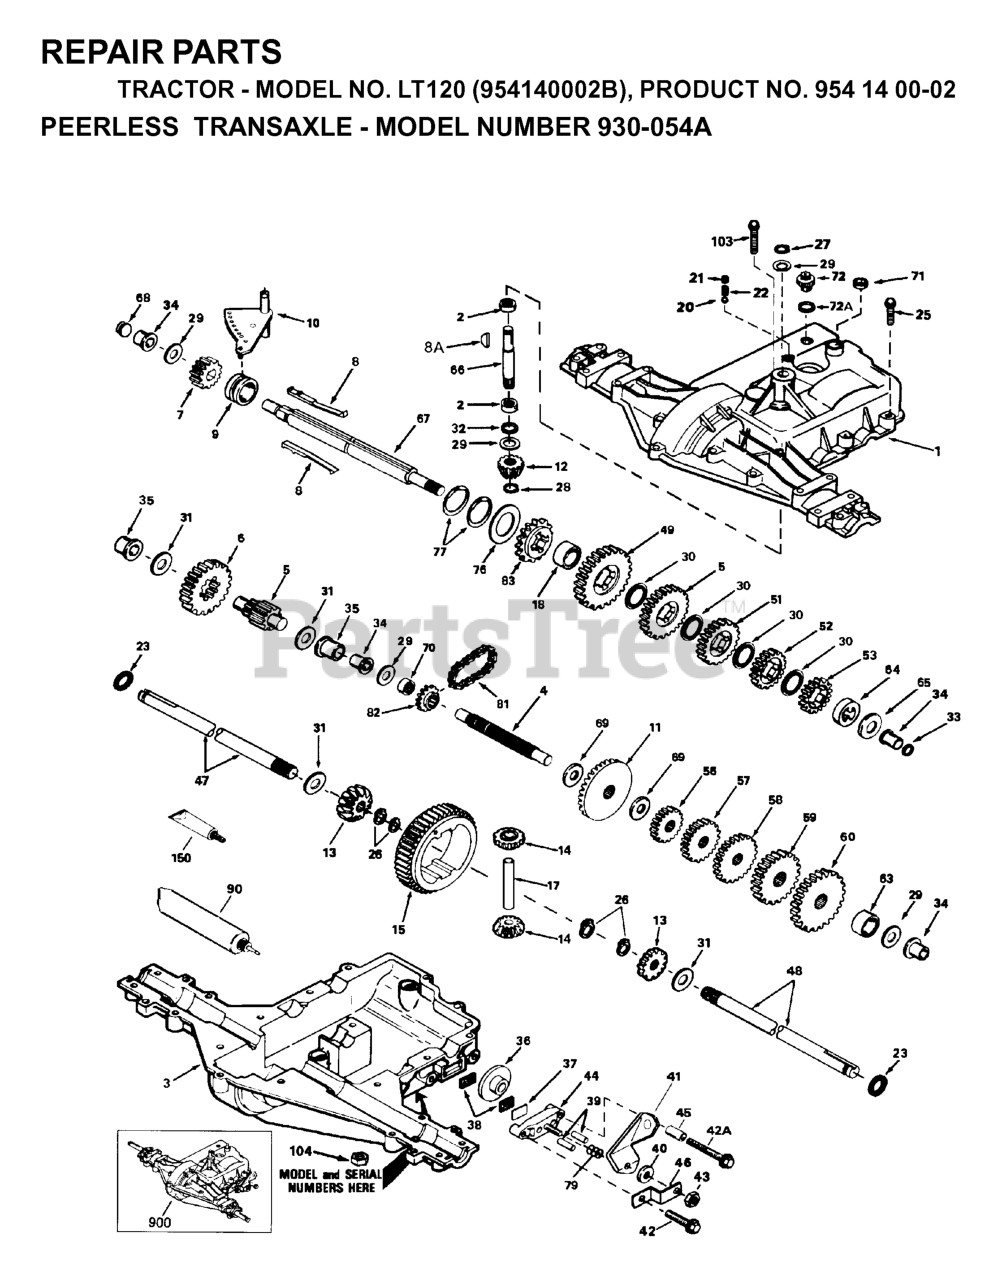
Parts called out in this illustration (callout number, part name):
2	Bearing, Needle
4	Shaft, Counter
8A	Woodruff Key No. 9
9	Collar, Shifter
11	Bevel Gear (42 teeth-steel)
15	Gear, Ring
18	Spacer, Neutral
20	Ball, Steel 5/16" diameter
21	Set Screw 3/18-16 x 3/8"
23	Ring, Seal
26	Ring, Retainer (4 Required, Package of 2)
27	Retaining Ring
28	Ring, Retaining
29	Washer, Thrust
30	Washer, Thrust
31	Washer (.056 wide)
33	Seal, Square Cut
36	Disk, Brake
37	Plate, Brake pad
38	Brake Pad (pkg of 2)
39	Pin, Dowel
40	Washer, Flat
41	Lever, Brake
42	Screw, Flanged Hex Head, Thread Forming 1/4-20 x 1-1/4
42A	Screw, 1 /4-20 x 2-1 /4"
43	Lock Nut 5/16-24
44	Holder, Brake pad
45	Spacer (1/2" OD)
46	Bracket, Brake lever
47	Axle (11-15/16" long)
48	Axle (16-1/2" long)
49	Gear, Spur, 37 Teeth, Steel (1 st)
53	Gear, Spur, 19 Teeth, Steel (4 th)
56	Gear, Spur, 12 Teeth (1 st)
60	Gear, Spur, 31 Teeth (5 th)
63	Countershaft Spacer (1-1/8" x 3/8")
64	Brake Shaft Spacer (1-3/8" x 3/8")
66	Input Shaft (3.687" long)
69	Thrust Washer (.762 ID)
71	Seal, Square Cut
76	Washer, Thrust
77	Ring, Retaining, Inverted (Package of 2)
79	Piston Assembly
81	Chain, Roller (Number 41 Chain, 24 Links)
150	Gasket Eliminator (Loctite No. 515)
